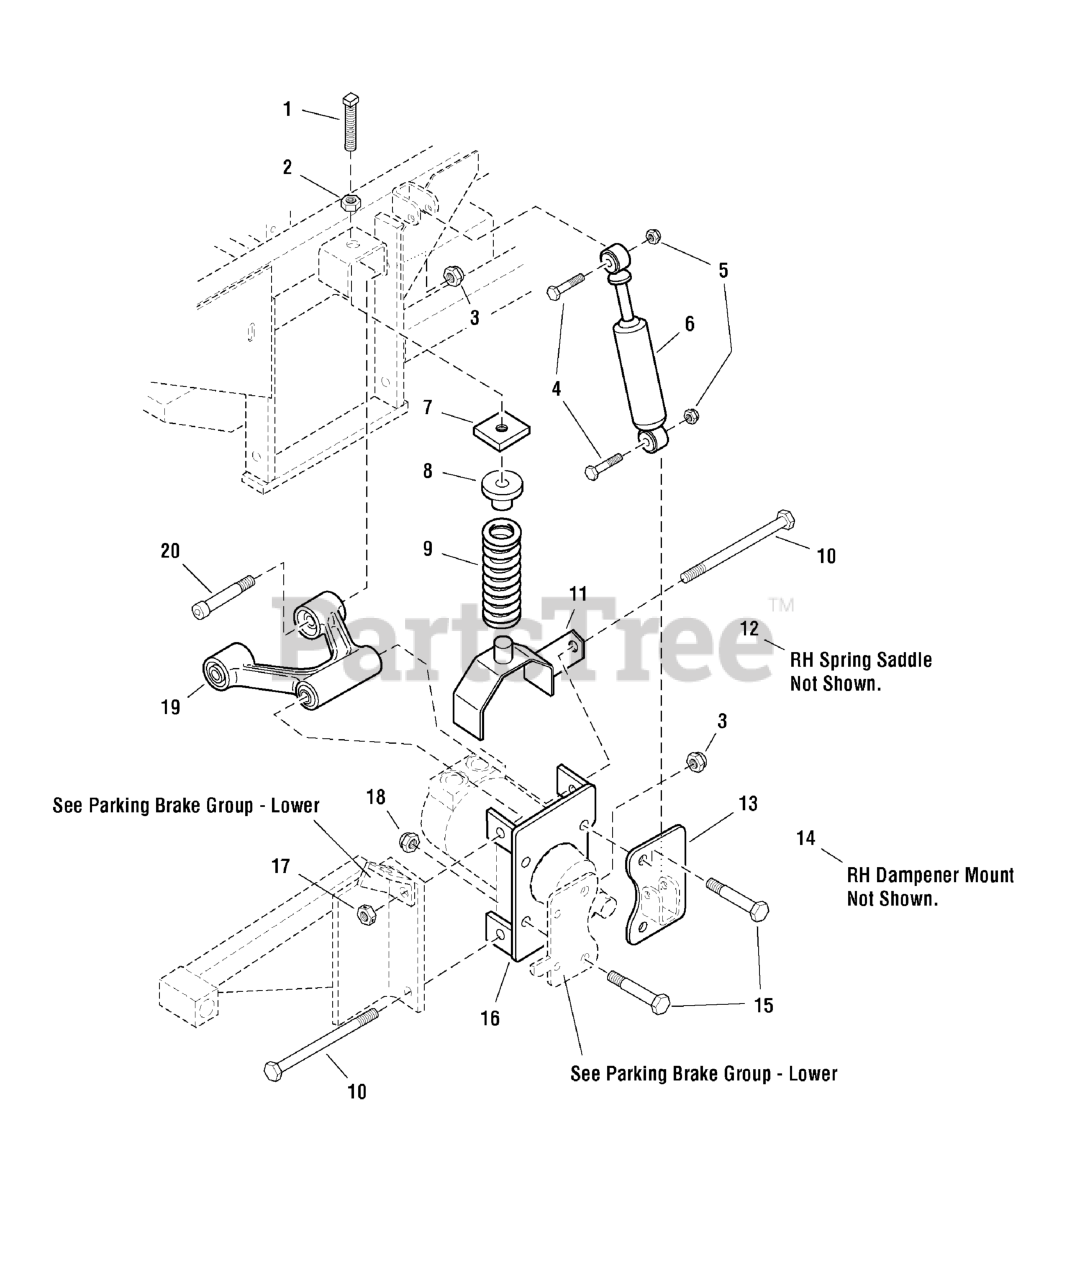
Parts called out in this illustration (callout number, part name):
1	SET SCREW, Square Head, 1/2-13 x 3
2	NUT, Hex, Jam, 1/2-13
3	NUT, 1/2-13 HEX NYLON LOCK
4	BOLT, 3/8-16 X 2, GD5, CZ
5	NUT, 3/8-16 HEX NYLON LOCK
6	KIT, SHOCK W/OUT COIL
7	SPRING COMPRESSION PLATE
8	SPRING RETAINER
9	SPRING, Compression
10	BOLT, HEX, 1/2-13 X 6-1/2, GD 8, YZ
11	SPRING SADDLE-LH
13	DAMPENER MOUNT - LH
15	BOLT, 1/2-20 X 3" GD5 YZ
16	WHEEL MOTOR MOUNT
17	NUT, 1/2-13 Hex Side Lock
18	NUT, Hex, Nylon Lock, 1/2-20
19	ASSM, A-ARM WITH BEARINGS
20	SET SCREW, Square Hd, 1/2-13 x 3
